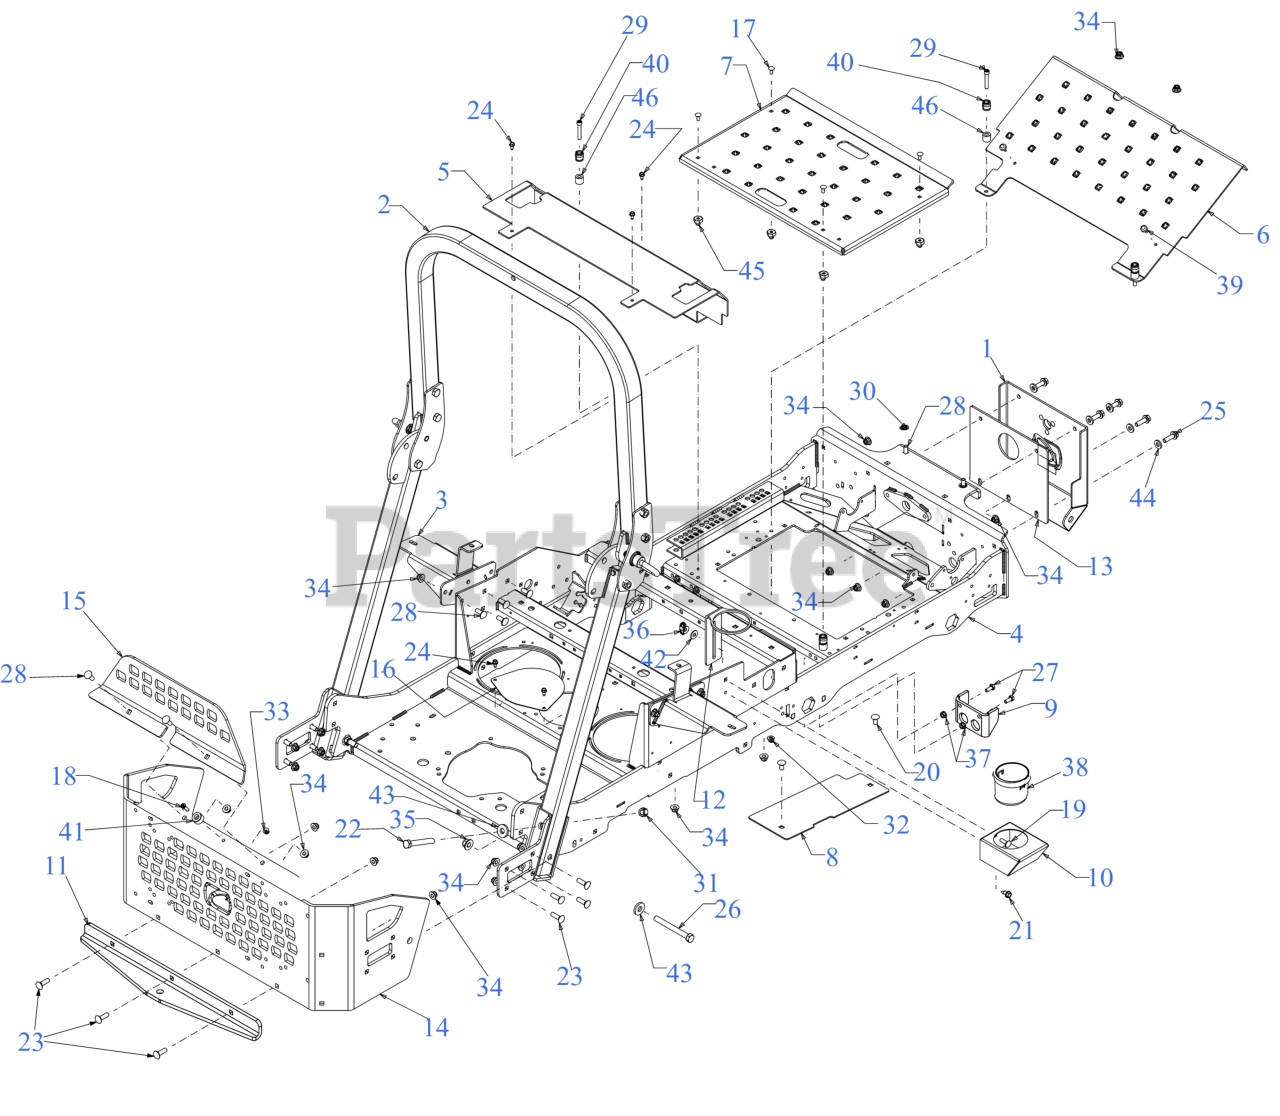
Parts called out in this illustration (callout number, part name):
2	PRO Z ROPS KIT
3	FUEL TANK MOUNT
4	FRAME
13	FRONT MOUNTING PLATE SPACER
14	BUMPER (LOWER RR)
15	BUMPER (UPPER RR)
16	FRAME COVER PLATE
17	CARRIAGE BOLT 1/4-20 x .62
18	MACHINE SCREW 1/4-20:1
19	CARRIAGE BOLT 5/16-18 x 1.00
20	CARRIAGE BOLT 3/8-16 x .750 GR5
21	SCREW 5/16-18 x .750
22	SCREW 1/2-20 x 3.50 GR5
23	CARRIAGE BOLT 3/8-16 X1.25 GR5
24	SCREW 1/4-20 X.500
25	SCREW 3/8-16 x 1.25 GR5
26	SCREW 1/2-13 x 4.5 GR 5
27	SCREW 5/16-18 x .75 GR5
28	CARRIAGE BOLT 3/8-16 x 1.00 GR5
29	SCREW 5/16-18X1.75 GR5
32	FLANGE LOCK NUT 5/16-18
33	FLANGE LOCK NUT
36	WING NUT 5/16-18
37	FLANGE NUT
39	BUMPER, .62 DIA x .3
40	RADIAL BUMPER
42	FLAT WASHER
43	FLAT WASHER .531 x 1.25 x .181
44	FLAT WASHER
45	SHOULDER SPACER
